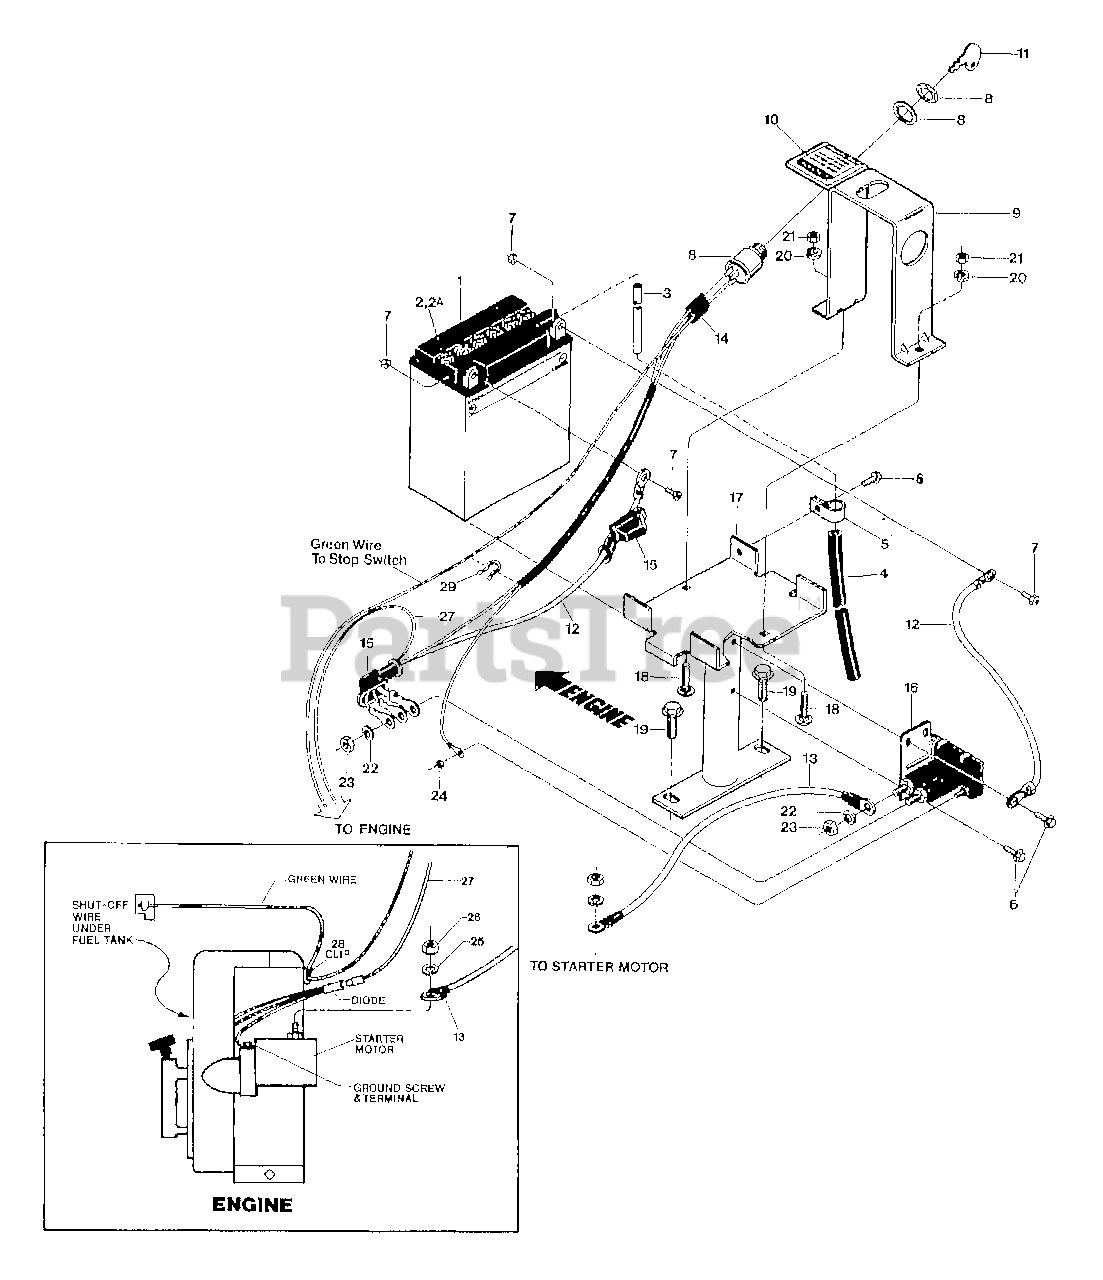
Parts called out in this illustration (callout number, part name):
1	BATTERY - 12 VOLT, 12 AMPHERE (INCL. 7)
2	CAP-YELLOW
2A	CAP-BATTERY WHITE (PONY)
3	TUBE-VENT BATTERY/HSE
4	TUBING-RUBBER (HARD PLASTIC)
5	CLAMP
6	SCR-HWH 1/4-20 X .5 STH
7	HDW PKG-BATTERY TERMINAL
8	ASSM-KEYSWITCH W/DECAL
9	KEY PLATE/CLAMP PNT
10	DECAL-KEYSWITCH
11	KEYS(1 PAIR) FOR SWITCH
12	CABLE-BATTERY-12"
13	CABLE-BATTERY 12"
14	ASSM-HARNESS 2647/20857 (AVAIL. AS COMPLETE ASSEMBLY ONLY).
15	BOOT-BATTERY CABLE
16	SOLENOID (INCL. NUTS & WASHER FOR CABLES AND WIRES)
17	BRKT-BATTERY OPC PNT
18	SCR-CARR 1/4-20X1.25
19	SCR-HFLK 5/16-18X1.00 ZP
20	WASHER-LK .25 ZP
21	NUT-HEX 1/4-20 ZP
22	WASHER-LK .312 ZP
23	NUT-HEX 5/16-24
24	NUT W/LKWASHER #10-32 ZP
25	LOCKWASHER - #10 (NOT AVAIL. FROM FACTORY)
26	NUT - HEX, #10-24 (NOT AVAIL. FROM FACTORY)
27	WIRE-RECHARGE 5&7 BRIGGS
28	CLIP-SPECIAL
29	TIE-TWIST LOCK
